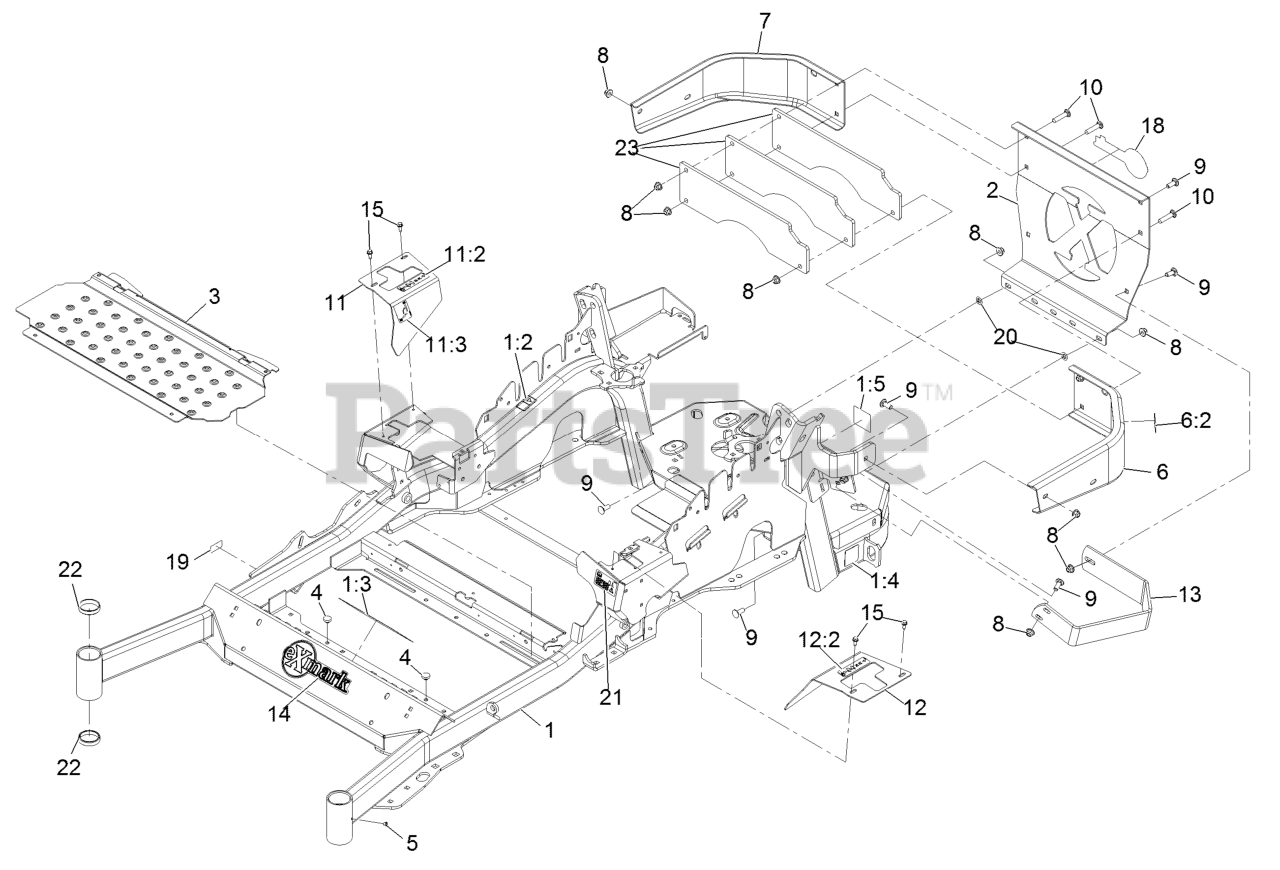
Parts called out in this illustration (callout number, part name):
1	Mainframe ASM, Rd W/Decals
1:2	Decal-Warning
1:3	Decal-Danger
1:4	Decal-Hazard, Pinched Finger
1:5	Decal-Spark Arrester
2	Plate,Rear Guard
6	LH Bumper ASM
6:2	Decal-Warning
7	Bumper-RH
8	Nut-Nyloc 3/8-16 Flg
9	Bolt-Carriage 3/8-16 X 1
10	Bolt-Carriage 3/8-16 X 1 3/4
11	RH Motion Control Cover ASM
11:2	Decal-Control, Motion
11:3	Decal-Park Brake, CE
12	LH Motion Control Cover ASM
12:2	Decal-Control, Motion
13	Guard-Muffler
14	Decal-Exmark Logo
15	Screw-HWH 1/4-20 X .62
18	Decal-Exmark Logo
19	Decal-Patent
20	Nut-Push 3/8-16
21	Decal-Fuel Fill, CE
22	Cup-Bearing Tapered Roller
23	Weight-6 Lb Plate
